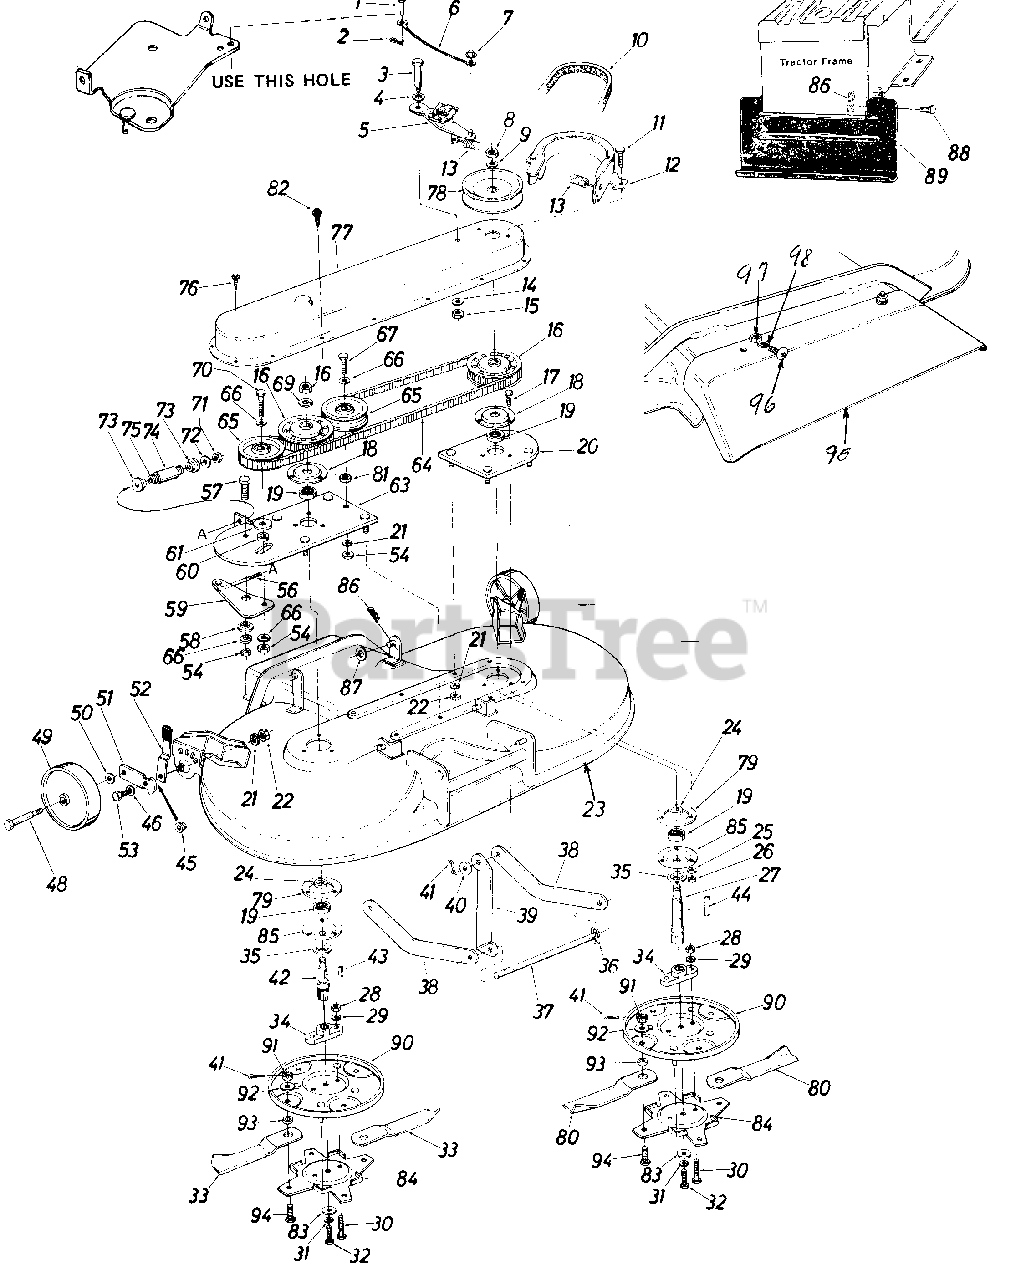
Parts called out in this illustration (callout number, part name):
1	Clevis Pin 1/4" Dia. x 1/2" Lg.
2	Hairpin Cotter 1/4" Dia.
3	Shld. Bolt.437" Dia. x.180" Lg. (5/16-18)
4	Wave Washer 7/16" Scr.
5	Spindle Brake Arm Ass'y.
6	Brake Cable Ass'y.
7	Push Cap 1/4" Stud.
8	Hex Jam Nut 5/8-18 Thd.
9	Bell.-Wash. 5/8" I.D. x 1.25" O.D.
10	"V"-Belt 1/2" x 56" Lg.
11	Hex Wash. Hd. Self Tap Scr. 1/4-20 x .50 " Lg .
12	Belt Guard
13	Extension Spring
14	Bell.-Wash..340" I.D.
15	Hex Cent. L-Nut 5/16-18 Thd.
16	Sprocket Pulley Ass'y.
17	Hex Bolt 5/16-24 x 1.00" Lg. (Grade 5)
18	Bearing Housing
19	Ball Bearing .787" I.D. x 1.85" O.D.
20	Spindle Plate Ass'y.
21	L.-Wash. 3/8" I.D.*
22	Hex Jam Nut 3/8-24 Thd.
23	44" R.D. Deck Ass'y.
24	Spacer
25	L.-Wash. 5/16" I.D.*
26	Hex Nut 5/16-24 Thd.*
27	Blade Spindle-L.H.
28	Hex Nut 5/16-24 Thd.*
29	L.-Wash. 5/16" I.D."
30	Hex Bolt 5/16-24 x 1.00" Lg.
31	L-Wash. 3/8" I.D., H.D.
32	Hex Bolt 3/8-24 x .88" Lg. (Grade 5)
33	Blade-L.H. Rotation
34	Blade Adapter
35	Bearing Shield
36	Hairpin Cotter
37	Deck Connecting Rod
41	Cotter Pin 3/32" Dia. x 1.00" Lg. *
42	Blade Spindle-R.H.
43	Sq. Key 3/16" x 75" Lg.*
44	Sq. Key 3/16" x 1.50" Lg.*
45	Shoulder Spacer
46	Bell.-Wash. .400" I.D.
48	Shld. Bolt 3/8-16 x 1.41" Lg.
49	Wheel Ass'y. Comp. 6" x 1.38
50	Bell-Wash. 3/8" I.D.
51	Wheel Pivot Bar
52	Spring LeverAss'y. w/knob
53	Hex Bolt 3/8-24 x 1.25" Lg. Grade 5
54	Hex Cent. L-Nut 3/8-24 Thd.
56	Adjustment Link 5/16-18 x 4-9/16" Lg.
57	Hex Bolt 3/8-24 x 1.00"
58	Shld. Spacer .625" I.D.
59	Belt Idler Brkt.
60	Spacer.380" I.D. x .625" O.D. x .265
61	Fl.-Wash. .38" I.D. x 1.37" O.D. x .125
63	Spindle & Idler Mount Plate Ass'y.
64	HTD Twin Power Belt
65	Fl.-IdlerPulley 3.50" O.D.
66	Bell.-Wash..38" I.D.
67	Hex Bolt 3/8-24 x 1.75" Lg. (Grade 5)
69	Bell.-Wash. 5/8" I.D.
70	Hex Bolt 3/8-24 x 2.00" Lg.
71	Hex Insert L.-Nut 5/16-18 Thd.
72	Fl.-Wash. 344" I.D. x 1.125" O.D. x .125
73	Shld. Spacer.625" I.D.
74	Spacer-Adj. Bolt
75	Compression Spring
76	Hex Wash. Hd. Self Tap. Scr. 1/4-20 x .50" Lg.
77	Belt Cover
78	Deck Drive Pulley
79	Deck Reinforcement Plate
80	Blade-R.H. Rotation
81	Fl.-Wash. .38" I.D. x 1.00"O.D.
82	Hex Wash. Hd. Self Tap-Scr. 1/4-20 x .75" Lg.
83	Flat Washer
86	Hairpin Cotter
87	Fl.-Wash. 1/2" I.D.
88	Clevis Pin
89	Safety Shield-16 5/8" Lg.
92	Fl.-Wash. .531" I.D. x 1.25" O.D.
93	Spacer
94	Shld. Scr. .50" Dia. x .36"
95	Chute Extension
96	Phil. Hd. Screw 1/4-20 x .50"
97	Hex Nut 14 20 Thd*
98	Lock Washer 1/4 I.D.*
